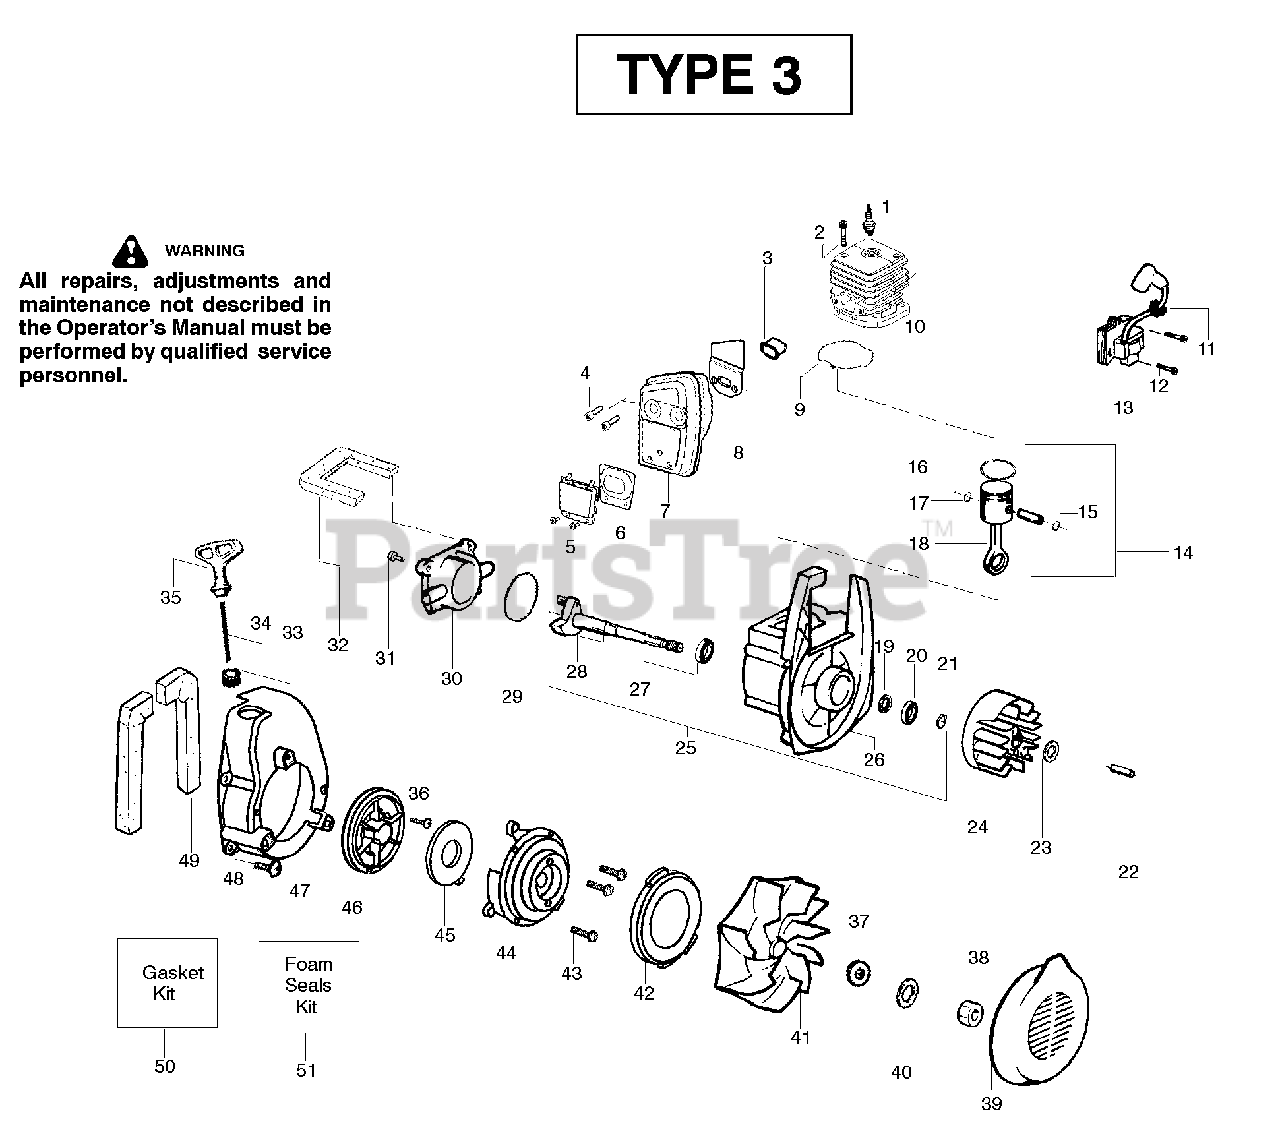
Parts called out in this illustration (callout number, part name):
1	Spark Plug (RCJ-6Y)
3	Insulator-Heat
4	Screw-Muffler-Internal
6	Kit-Spark Screen
7	Kit-Muffler
8	Gasket-Baffle (kit)
9	Gasket-Cylinder (kit)
11	Grommet-Ign. Module
12	Screw-Ignition Module
13	Ignition Module
14	Kit-Piston/Rod
15	Kit-Piston
16	Piston Ring
17	Retainer-Piston Pin
18	Assy-Connecting Rod
20	Bearing-Outer
21	Retainer Ring-C'chaft
22	Spacer-Flywheel
24	Assy-Flywheel
25	Assy-Crankcase/Crank shaft
26	Assy-Crankcase
27	Bearing-Inner
28	Assy-Crankshaft
29	O-ring-C/case (kit)
30	Cover-Crankcase
31	Screw
32	Foam-219mm (kit)
33	Eyelet-Flange
34	Kit-Rope
35	Handle-Starter
37	Washer-Belleville
41	Kit-Impeller Assy.
44	Housing-Pulley
45	Spring-Starter
46	Kit-Starter Pulley
48	Screw
49	Foam-182mm (kit)
50	Kit-Gasket
51	Kit-Foam Seals
